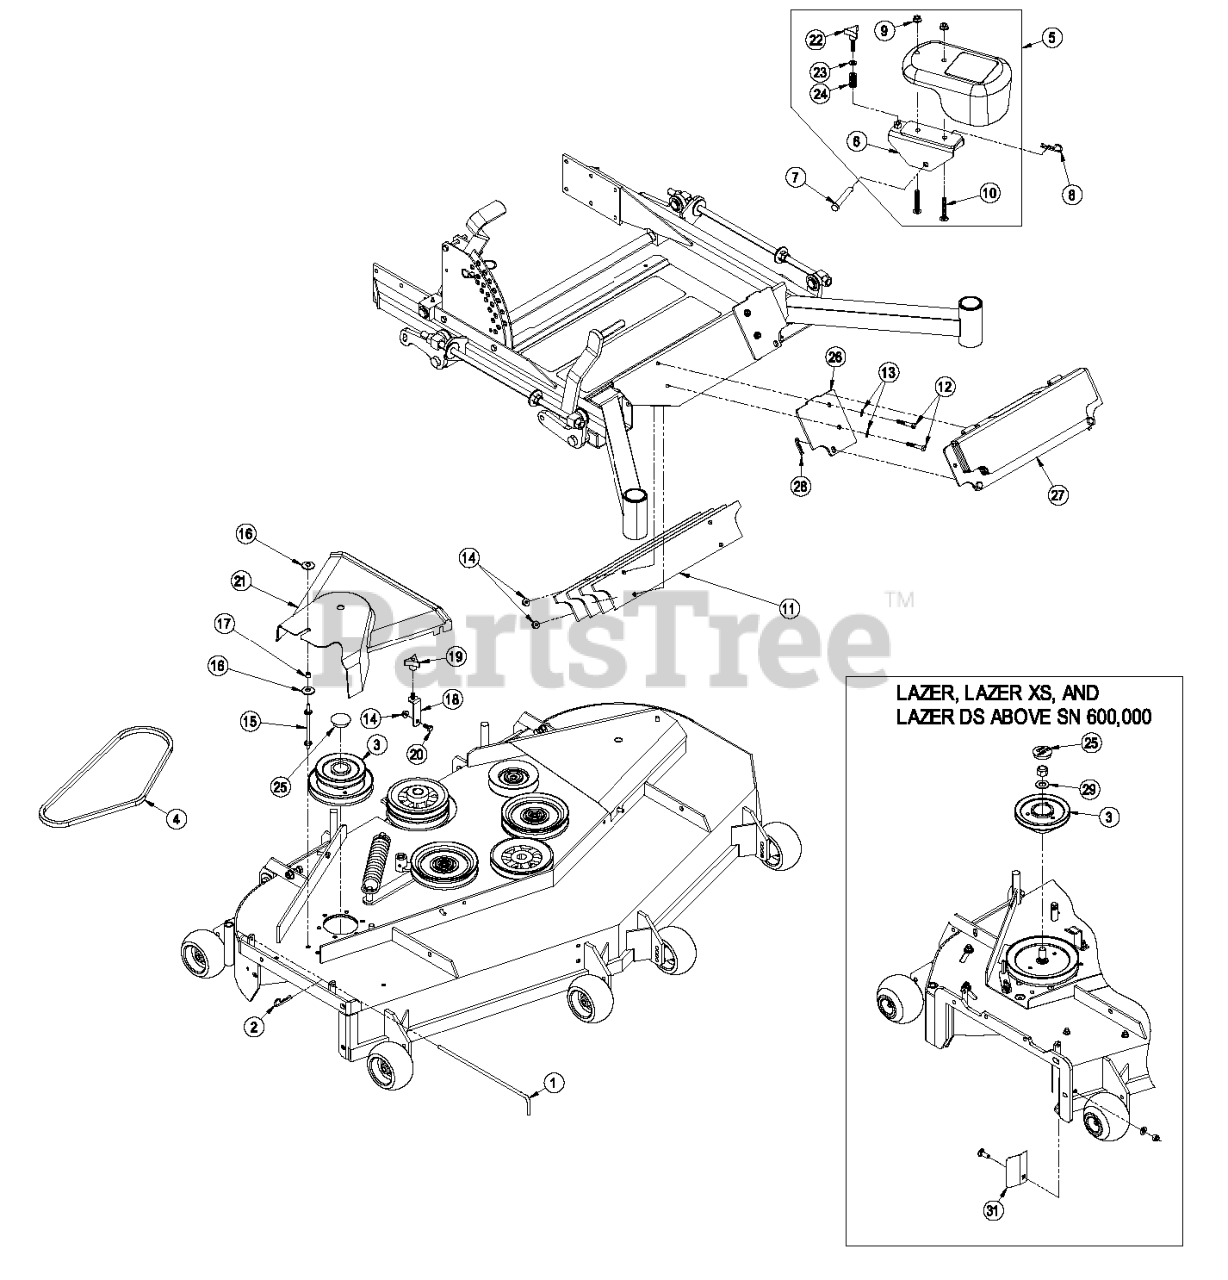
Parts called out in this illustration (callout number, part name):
1	PIN,CHUTE PIVOT
2	PIN-COTTER
3	JACKSHAFT, LZUV60
4	BELT, BLOWER 52"DECK
5	ASM, WEIGHT 1.5" 70 POUND
6	WLD, BRACKET 2.0 ARM
7	PIN-CLEVIS
8	PIN-COTTER
9	NUT-HHF, WHIZ
10	BOLT, SQUARE HEAD YZ
11	PLATE, WEIGHT
12	SCREW-HH
13	WASHER-PLAIN
15	STUD,BELT SHIELD 4 INCH
16	WASHER-SPRING
18	Support, Belt Cover
19	Knob
21	COVER, BELT LZ52
23	WASHER-FLAT
25	PLUG, BLACK NYLON 1.75
26	PLATE, WEIGHT MOUNTING
27	ASM, WEIGHT PLATE WITH DE
28	PIN-HAIR
29	Washer, 5/8 SAE
31	Deflector
